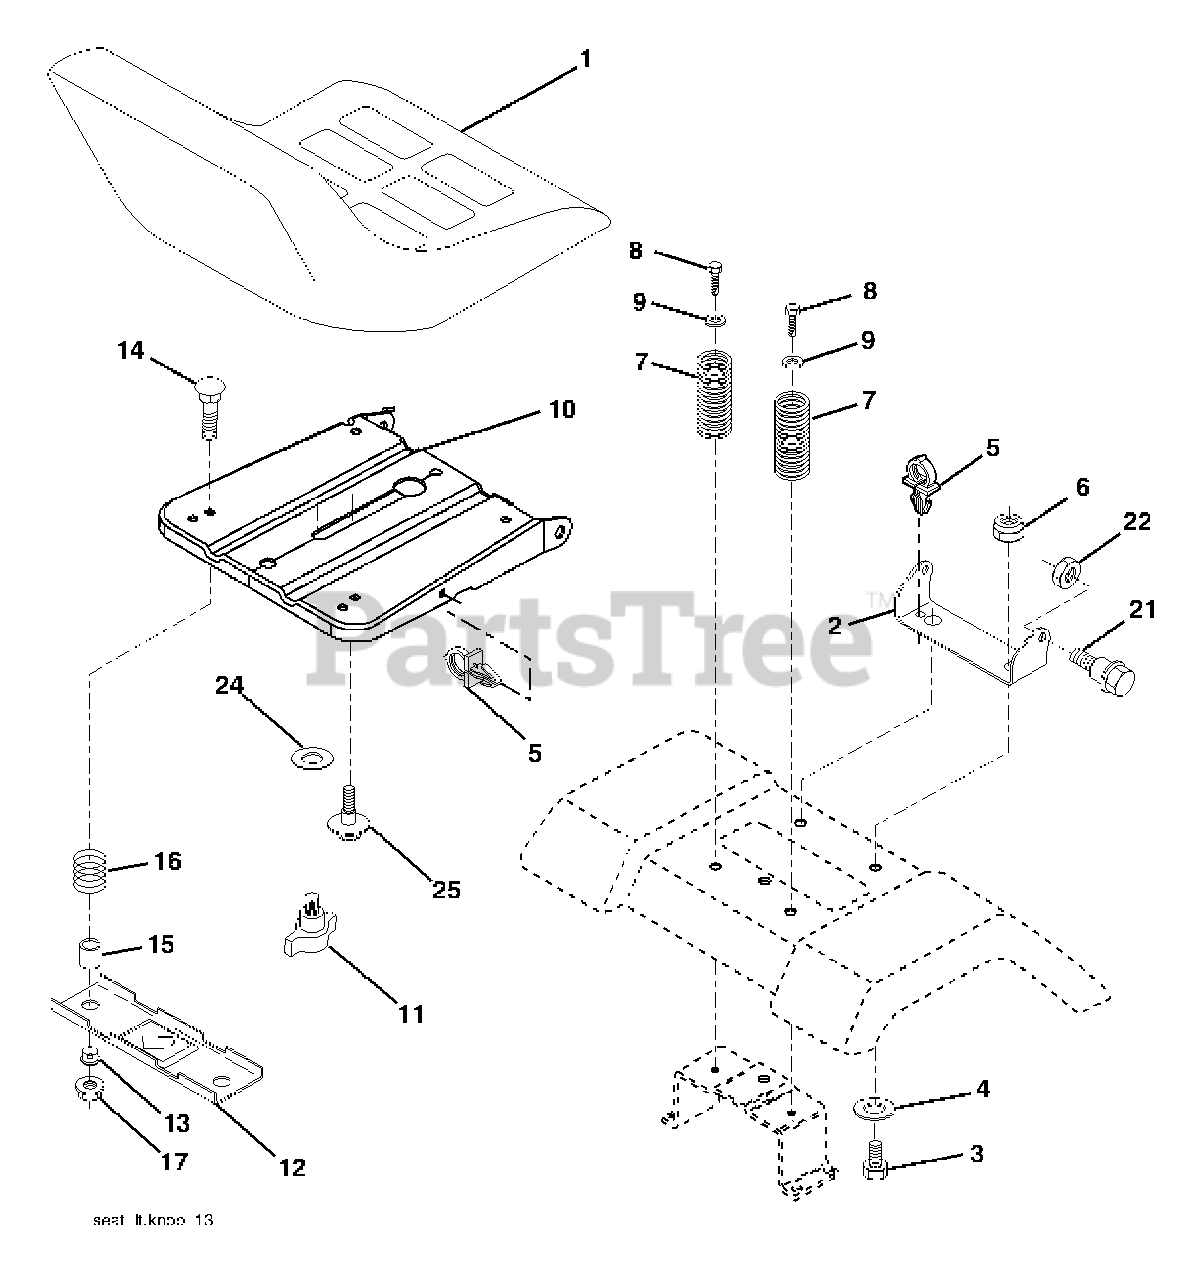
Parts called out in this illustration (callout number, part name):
1	Seat
2	Bracket Pivot Seat 8 720
3	Bolt Fin Hex 3/8-16 unc x 1
4	Washer Flat 13/32 x 1 x 10 Ga.
5	Clip Push-In
6	Nut Hex whns. 3/8-16 unc
7	Spring Seat Cprsn 2 250 Blk Zi
8	Screw 3/8-16 x 1
9	Washer 13/32 x 1 x 14 Ga.
10	Pan Seat
11	Knob Seat Adj. Wingnut
12	Bracket Mounting Switch
13	Bushing Snap Blk Nyl 50 Id
14	Bolt Rdhd Sqnk 1/4-20 x 1-1/2
15	Spacer Split
16	Spring Cprsn
17	Nut Lock 1/4 Lge Flg Gr. 5 Zinc
21	Bolt Shoulder 5/16-18 unc
22	Nut Hex Lock Wllns 5/16-18
24	Washer 17/32 x 1-3/16 x 12 Ga.
25	Bolt Shoulder 5/16-18 x 62
